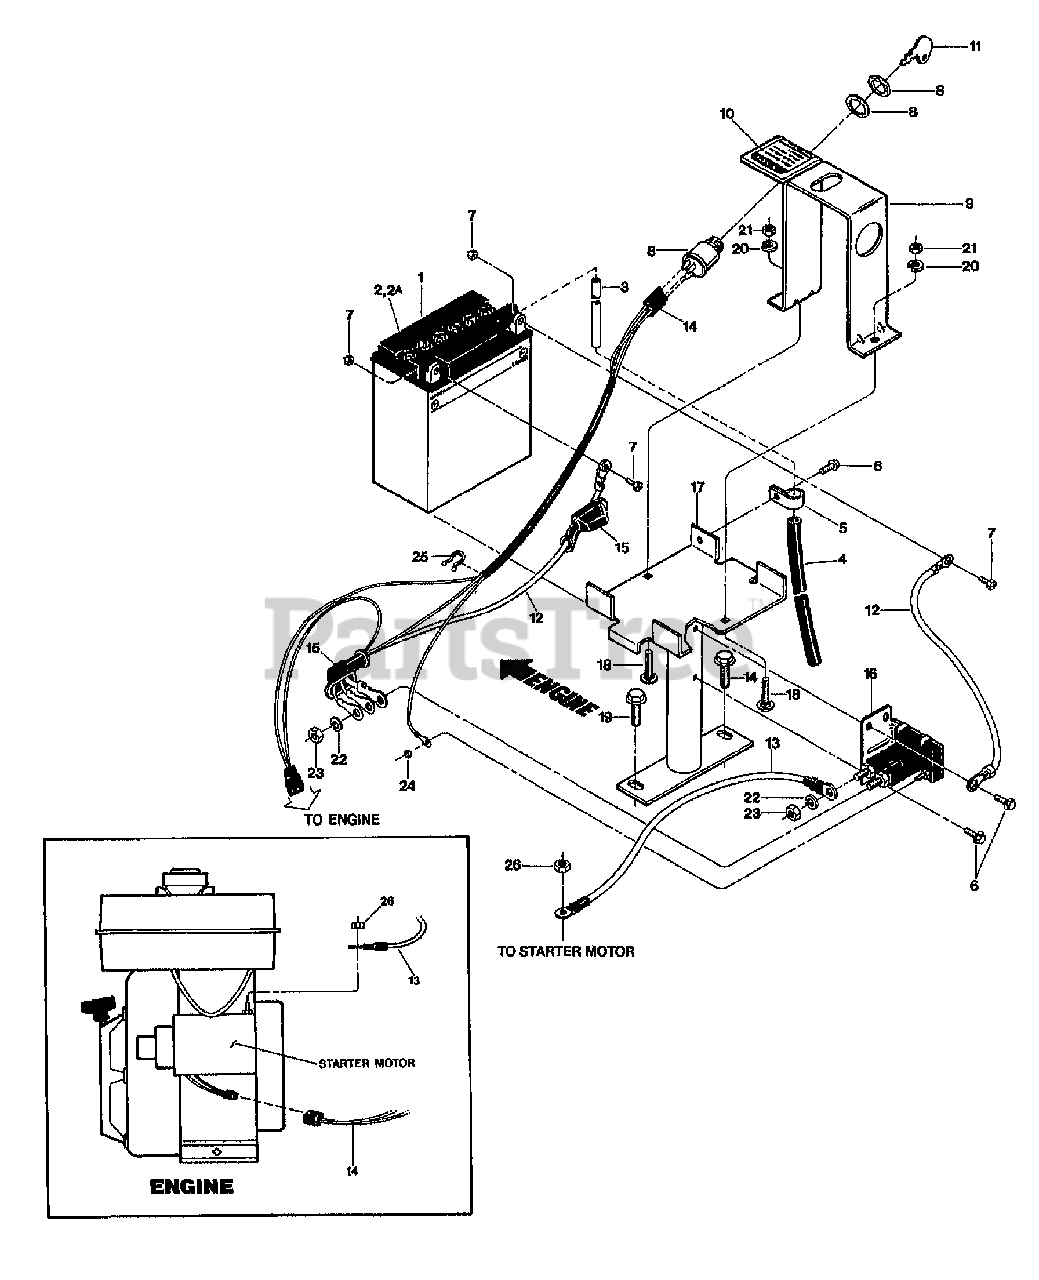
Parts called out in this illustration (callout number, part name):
1	BATTERY
2	CAP-YELLOW
2A	CAP-BATTERY WHITE (PONY)
3	TUBE-VENT BATTERY/HSE
4	TUBING-RUBBER
5	CLAMP
6	SCR-HWH 1/4-20 X .5 STH
7	HDW PKG-BATTERY TERMINAL
8	ASSM-KEYSWITCH W/DECAL
9	KEY PLATE/CLAMP PNT
10	DECAL-KEYSWITCH
11	KEYS(1 PAIR) FOR SWITCH
12	CABLE-BATTERY-12"
13	CABLE-BATTERY 14"
14	HARNESS-WIRE 3.5 (AVAILABLE AS COMPLETE ASSEMBLY ONLY)
15	BOOT-BATTERY CABLE
16	SOLENOID
17	BRKT-BATTERY OPC PNT
18	SCR-CARR 1/4-20X1.25
19	SCR-HFLK 5/16-18X1.00 ZP
20	WASHER-LK .25 ZP
21	NUT-HEX 1/4-20 ZP
22	WASHER-LK .312 ZP
23	NUT-HEX 5/16-24
24	NUT W/LKWASHER #10-32 ZP
25	TIE-TWIST LOCK
26	NUT-HF/LK 1/4-20 ZP
